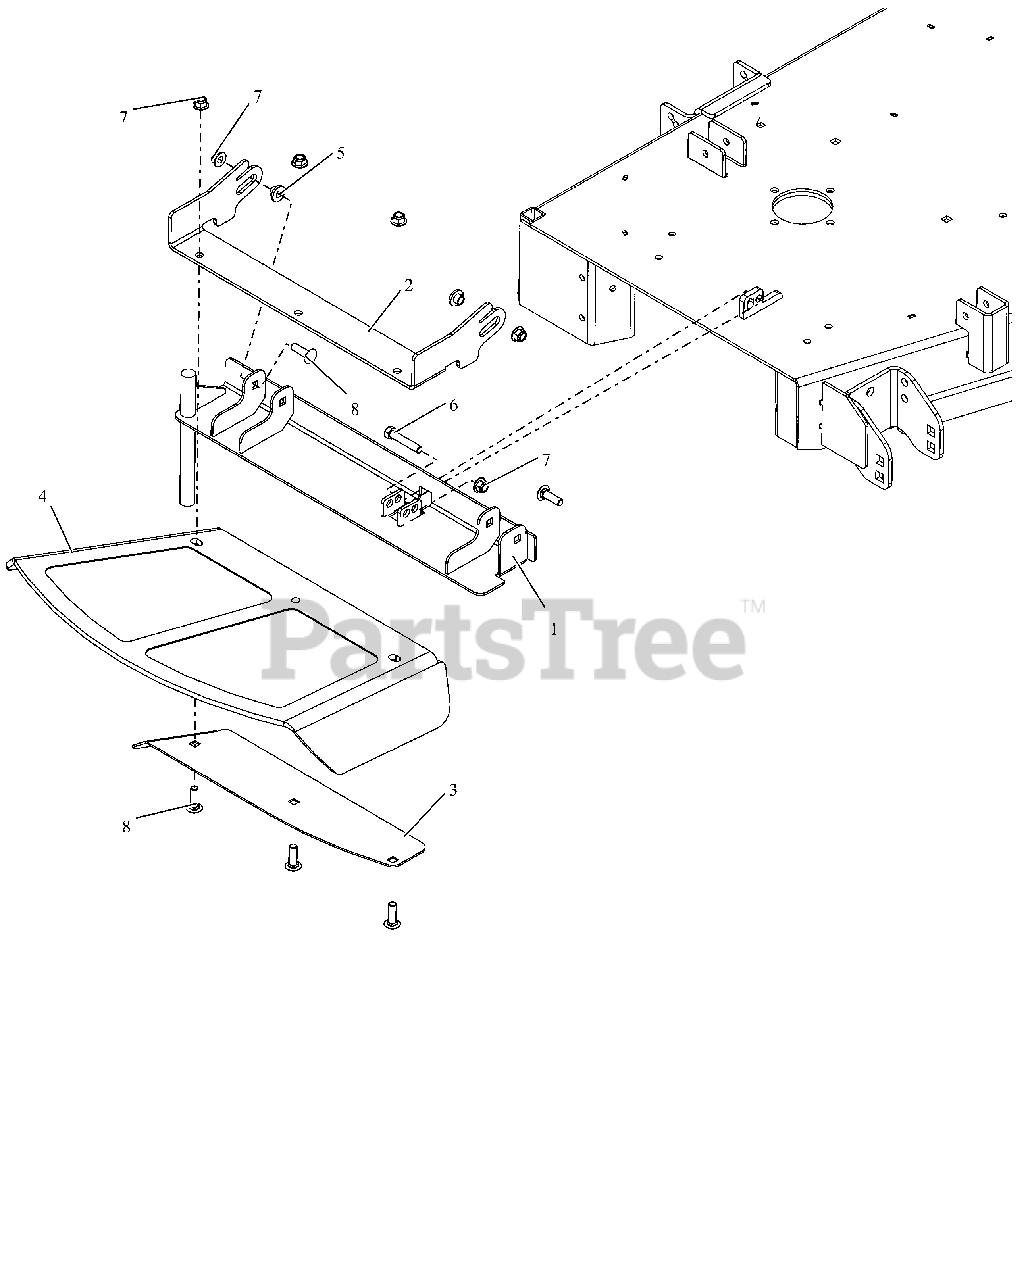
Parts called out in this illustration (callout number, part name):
1	48-60 DISCH CHT MTG WMT W/SAFE
2	48-60" CHUTE MTG BRKT - RED
3	48-60 DISCH CHUTE CLMP PLT-RED
4	CHUTE,48-60" FRMD RUBBER DISCH
5	BSHG-FLG .385X.500X.875X.406
6	BLT,HEX .38-16X2.00 G5 ZCC
7	NUT,NYL-FLG .38-16 GF ZCC
8	BLT,RHSSN .38-16X1.25 G5 ZCC
